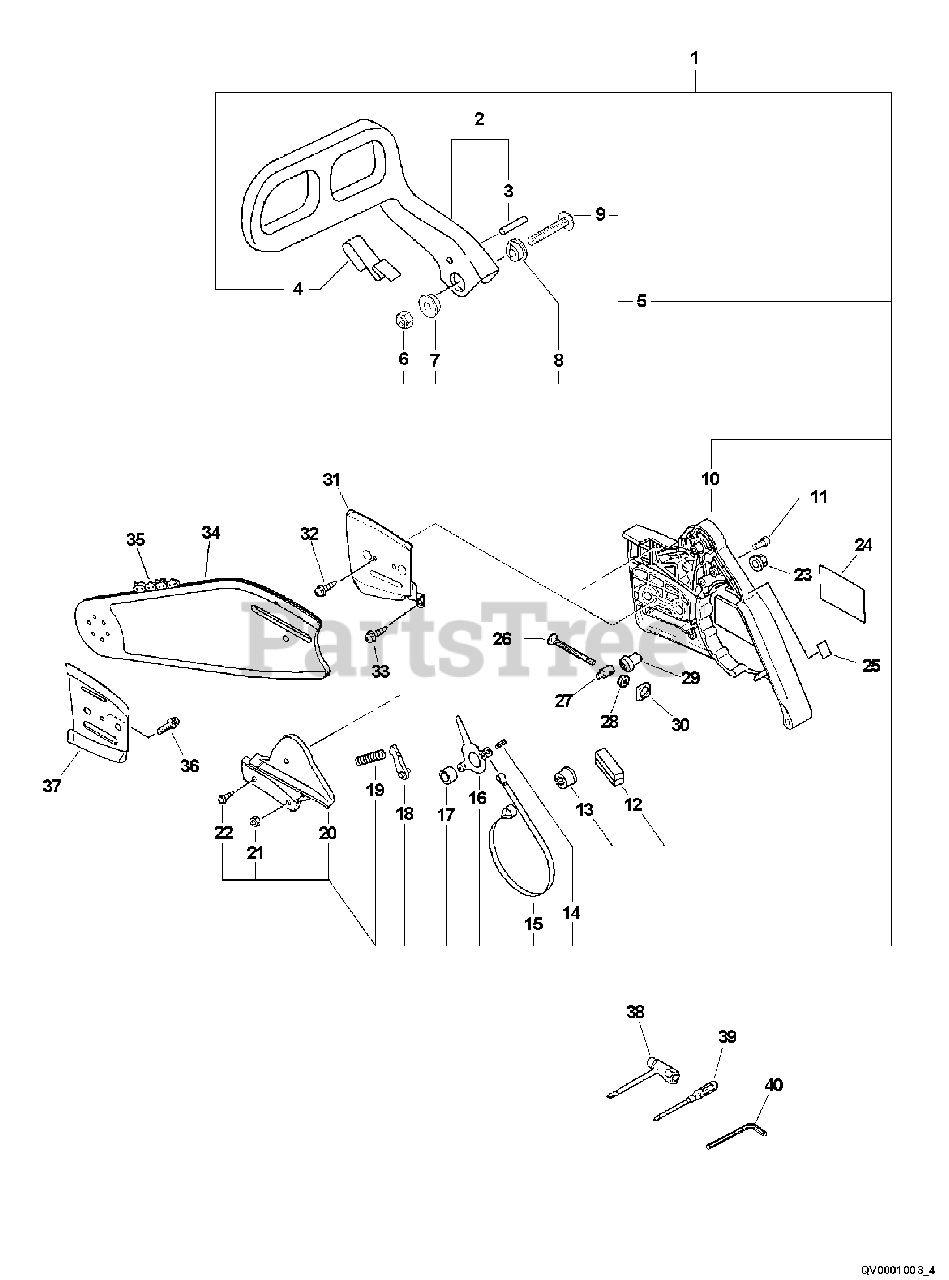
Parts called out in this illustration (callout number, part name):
1	CHAIN BRAKE ASSY
2	LEVER, BRAKE
3	PIN - 3.5X26
4	SPRING, RETURN
5	MOUNTING KIT
6	LOCKNUT - 5
8	COLLAR - 5
9	SCREW - 5X35
10	GUARD, SPROCKET
11	SCREW - 3X18
13	ADJUSTER, BRAKE BAND
14	PIN - SPRING -- 4X8
15	BAND, BRAKE
16	LEVER, BRAKE
17	SPACER - 8
18	STOPPER, BRAKE
19	SPRING, BRAKE
20	COVER, BRAKE
22	SCREW - 4X12
23	NUT - FLANGE
24	LABEL - ECHO
25	LABEL - CAUTION
26	SCREW, TENSIONER
27	TENSIONER, CHAIN
28	GEAR - BEVEL
29	GEAR - PINION
30	COLLAR - 8
31	PLATE, GUIDE - OUTER
32	SCREW - 3X6
33	SCREW - 4X10
34	GUIDE BAR - QUICKVENT
35	CHAIN -- CARBICHAIN QUICKVENT
36	SCREW - 4X8
37	PLATE, GUIDE - INNER
38	T-WRENCH - 13X19mm
39	SCREWDRIVER
40	HEX KEY - 4mm
